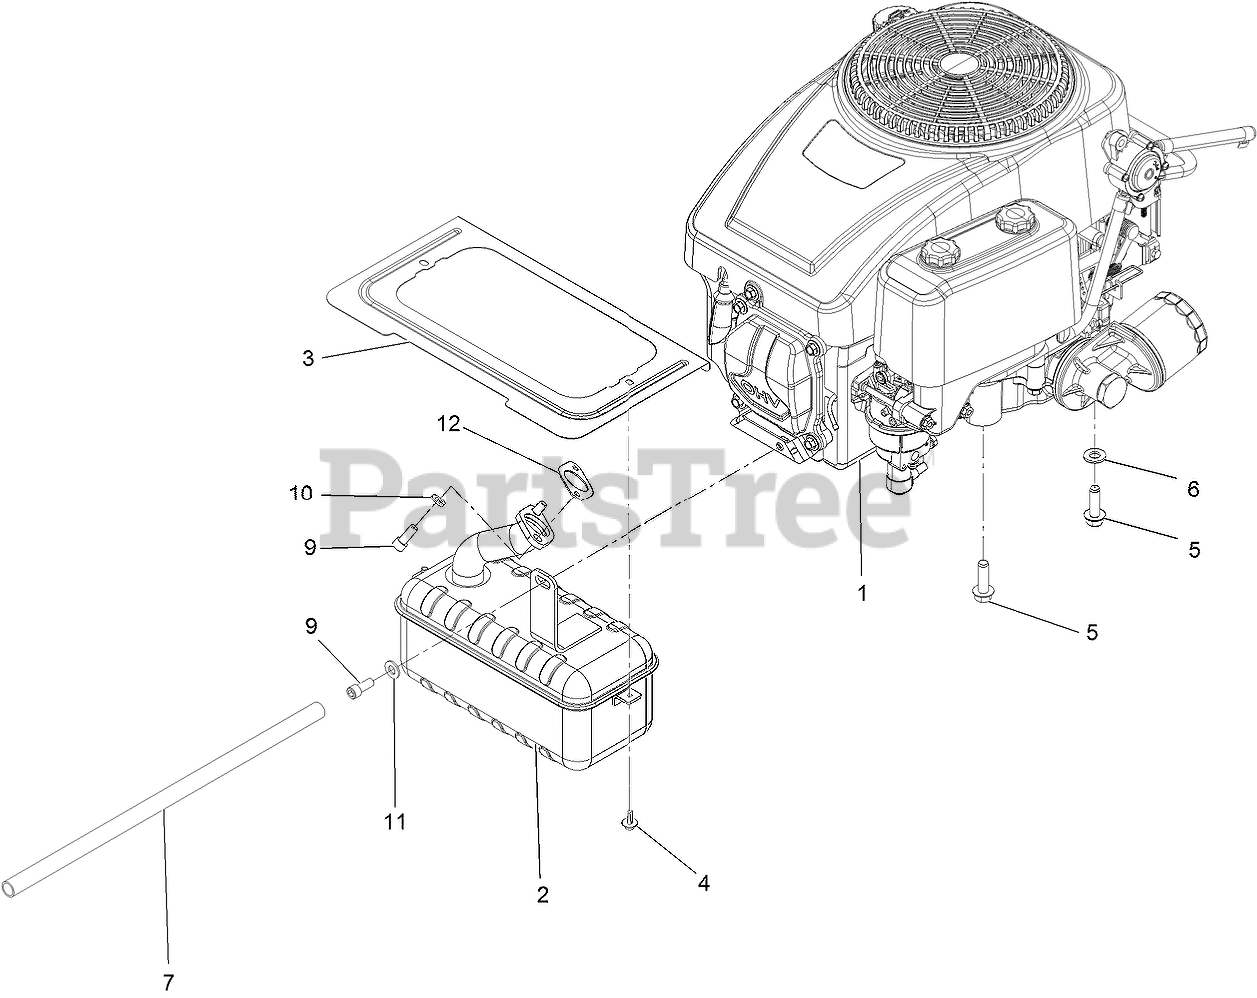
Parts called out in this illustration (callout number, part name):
1	ENGINE-LC1P92F-1
2	MUFFLER
3	SHIELD-HEAT
4	SCREW-HHFTF
5	SCREW-THD
6	WASHER-FLAT
7	TUBE-DRAIN, OIL
9	SCREW-HSH
10	WASHER-LOCK
11	WASHER-PLAIN
12	GASKET-EXHAUST
